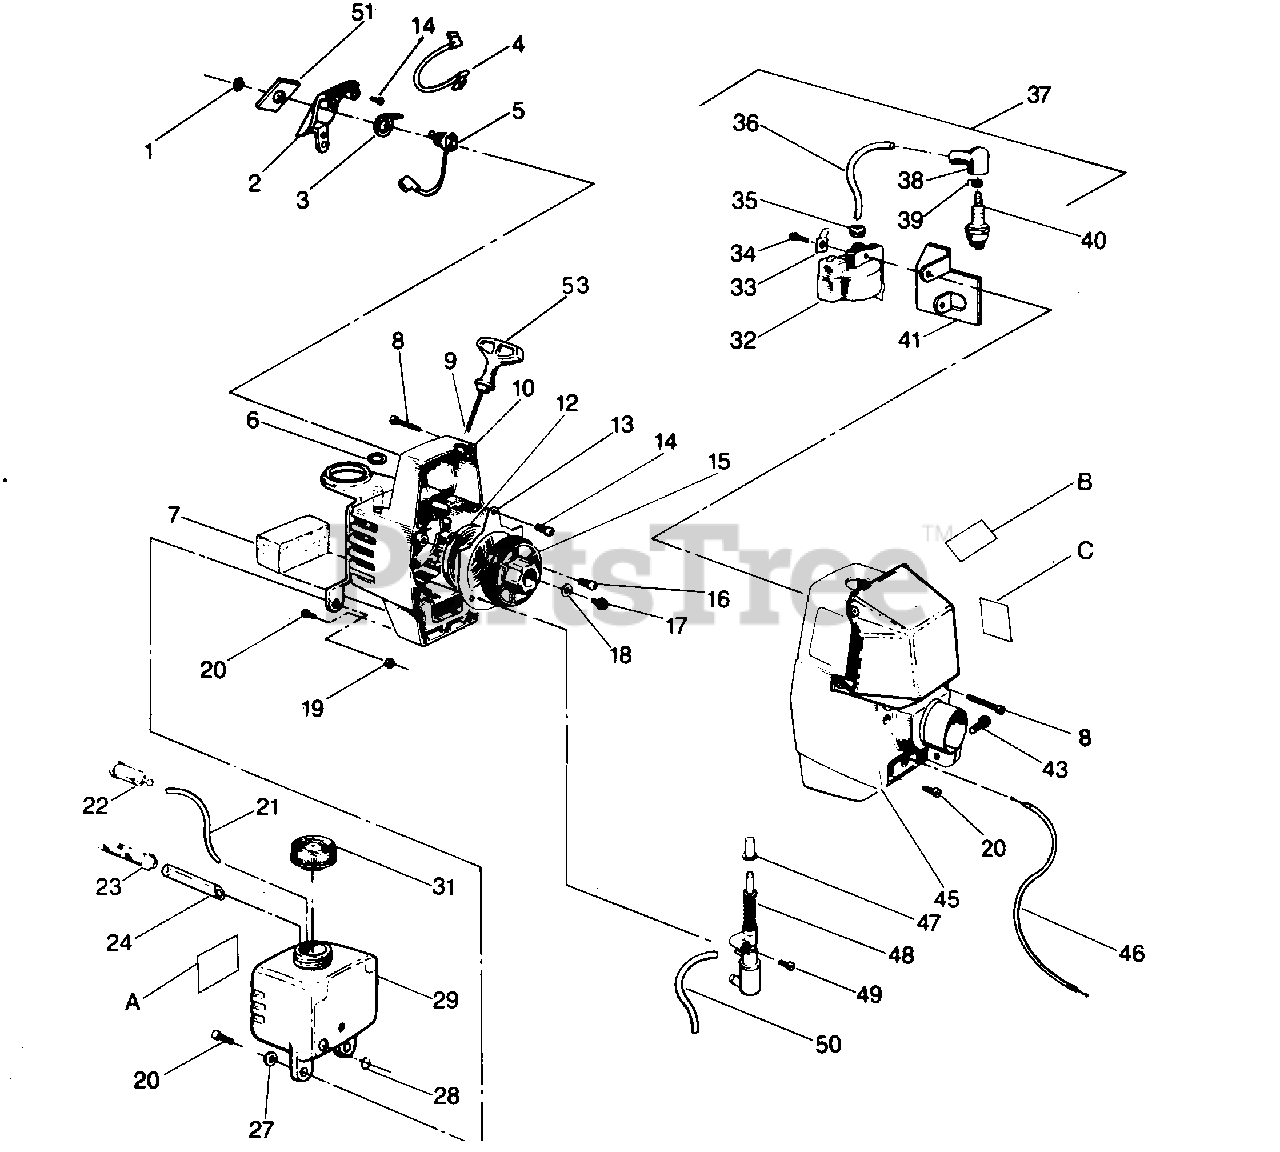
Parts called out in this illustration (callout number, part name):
1	Nut - Grounding Switch
2	Housing Switch
3	Washer - Grounding Switch
4	Wire - Lead - Grounding Switch
5	Kit - Grounding Switch (Inc.1,3,4,33)
6	Bearing - Nyliner (Fan Housing)
7	Air Filter
8	Screw - #10 - 24 x 1-1/2" Fil. Hd. - Fan Housing Top
9	Rope Kit
10	Fan Housing Kit
12	Spring Starter Pulley
13	Air Baffle
14	Screw - #10 - 17 x 3/8" Fil. Hd. - Air Baffle
15	Starter Pulley
16	Screw - #10 - 24 x 7/16" - Air Baffle
17	Screw - #10 - 24 x 1/2" - Starter Pulley
18	Washer - #10 - Starter Pulley Screw
19	Nut - #10 - 24 - Fuel Tank Bracket
20	Screw - #10 - 24 x 5/8" Fil. Hd. - Fan Housing Bottom/Fuel Tank
21	Line - Fuel Inlet
22	Fuel Pick-Up Assembly
23	Filter - Fuel (Inlet Line)
24	Fuel Line - Tank to Accumulator
27	Washer - Flat - Fuel Tank Bracket
28	Clip - Retainer - Inlet Line - Fuel Tank
29	Fuel Tank Assembly (Inc.21,22,23,24,31)
31	Fuel Cap Assembly (Incl. "O" Ring)
32	Kit Ignition Module
33	Electrical Tab
34	Screw - #8 - 32 x 3/4" - Fil. Hd. - Ignition Module
35	Grommet - Plug Wire
36	High Tension Lead Wire
37	BEVEL GEAR COMPLETE
38	Boot - Spark Plug
39	Connector - Spark Plug Lead
40	Spark Plug (CJ-14)
41	Deflector - Air
43	Bolt - #1/4 - 20 x 1" Hex - Pinch Clamp - Shroud
45	Ass'y. - Shroud/Heat Shield
46	Throttle Cable
47	Injector Button
48	Pump Assembly (Incl, #50)
49	Screw - #10 - 14 x 1-3/16" - Air Baffle - Pump Mounting
50	Line - Pump to Accumulator
51	Plate--Indicating Switch
A	Decal - Fuel Tank
B	Decal - Starting Instructions
C	Decal - Shroud (Left)
